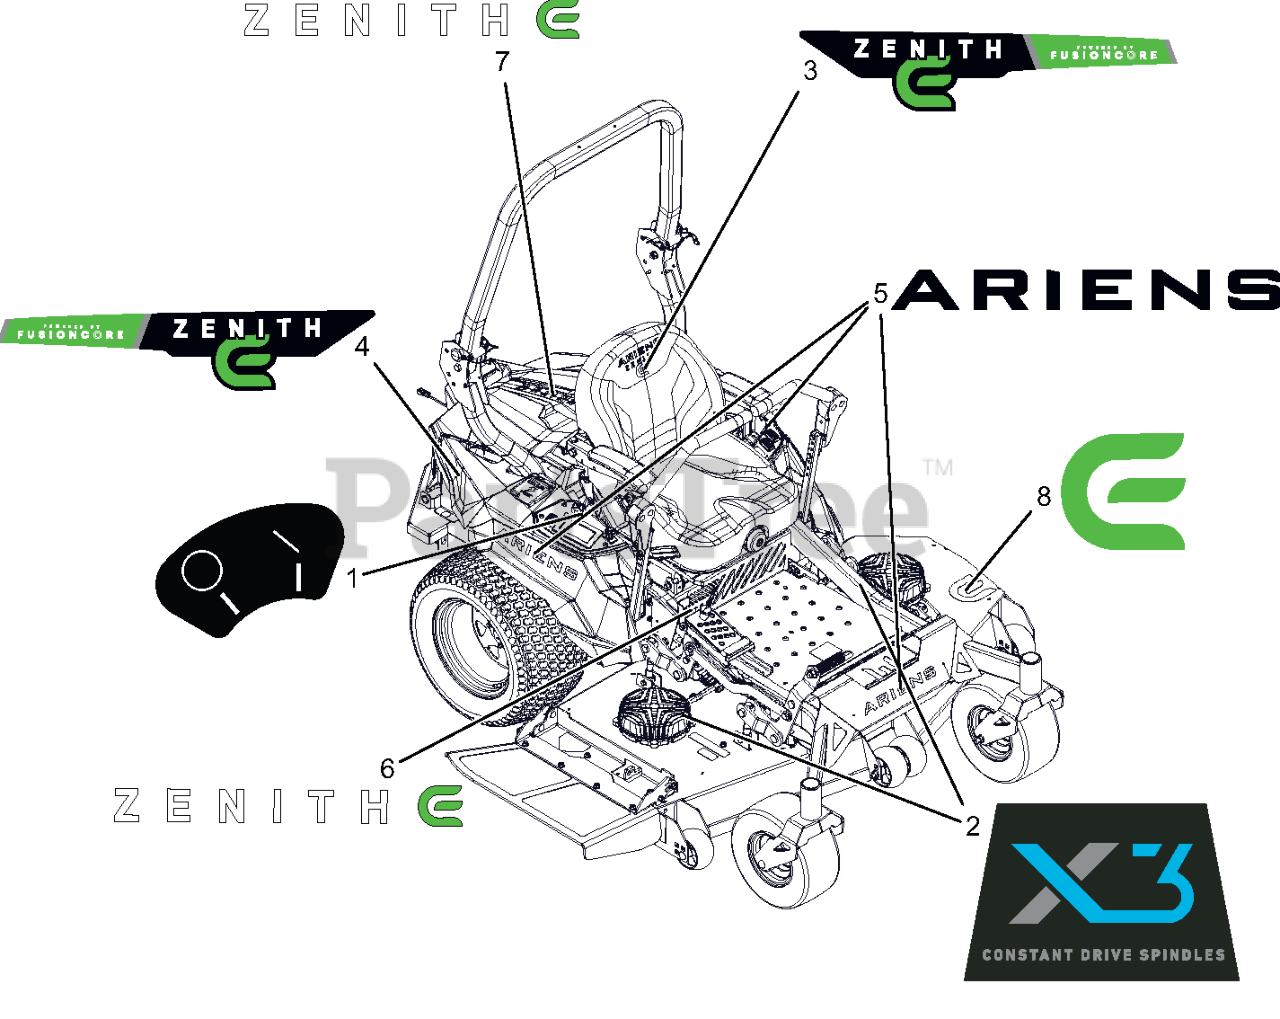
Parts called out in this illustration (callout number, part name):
1	DECAL, KEY SWITCH - 2 POS
2	DECAL, DECK MOTOR
3	DECAL, FENDER - ZENITH LH
4	DECAL, FENDER - ZENITH RH
5	DECAL, ARIENS - 12.0"
6	DECAL, KICKPLATE - ZENITH
7	DECAL, HOOD - ZENITH
8	DECAL, ZENITH - E
